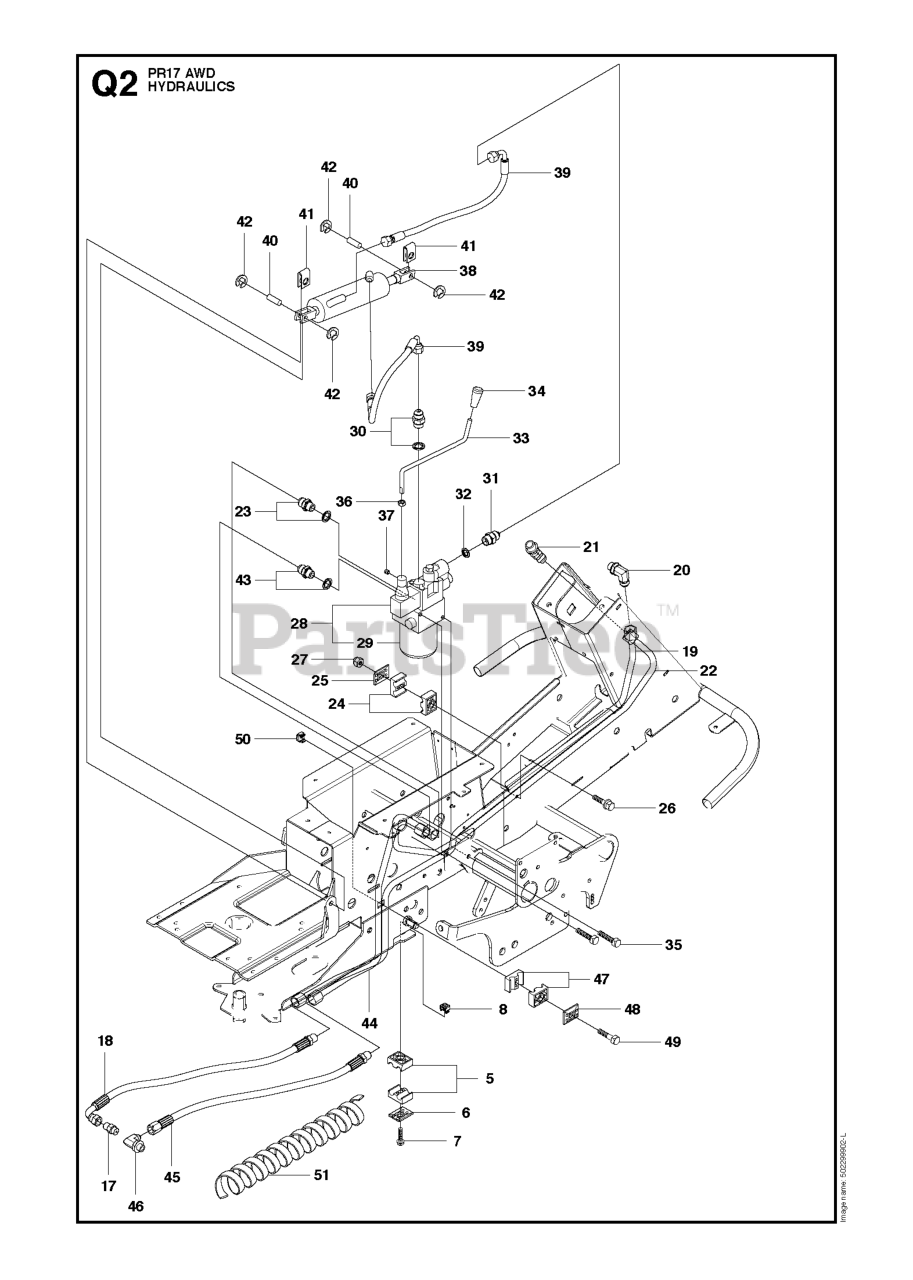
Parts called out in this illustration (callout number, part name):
5	PIPE CLAMP
6	COVER PLATE
7	SCREW EHHFM
24	PIPE CLAMP
27	LOCKNUT M6
29	FILTER
35	REPL BY 725 24 49-51
36	NUT
42	RETAINING RING SGA 10
47	PIPE CLAMP
51	HOSE GUARD D=43 L=400
